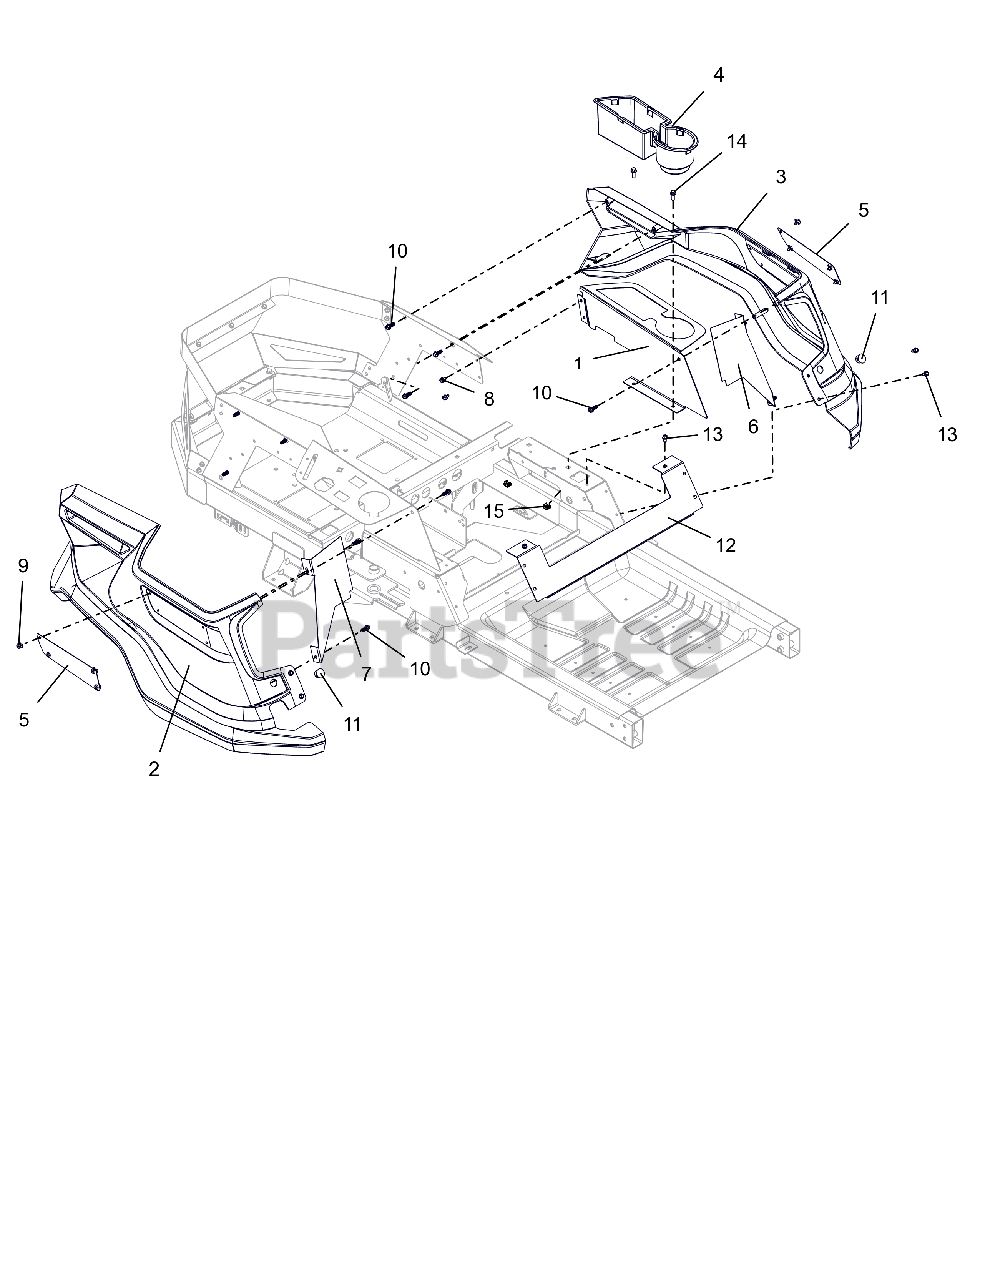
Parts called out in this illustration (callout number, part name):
1	PANEL, LEFT SIDE FENDER MOUNT
2	FENDER, RH IKON
3	FENDER, LH IKON
4	INSERT, CUP/STORAGE HOLDER
5	PLATE, ARIENS NAME
6	PLATE, LH BLOCKER
7	PLATE, RH BLOCKER
8	SCR,TAP .25-20X.375 HWH TR ZCC
9	RIVET, PLASTIC .195 DIA.
10	SCR-.312X.75 #14H H/W/H H/L CZ
11	PLUG, HOLE .75 (BLACK)
12	PLATE, SEAT KICK
13	SCR-TAP .25-20X.50 HWH ZCC
14	BLT,HEX-FLG .25-20X.75 G5 BFP
15	NUT RETNR .25-20
